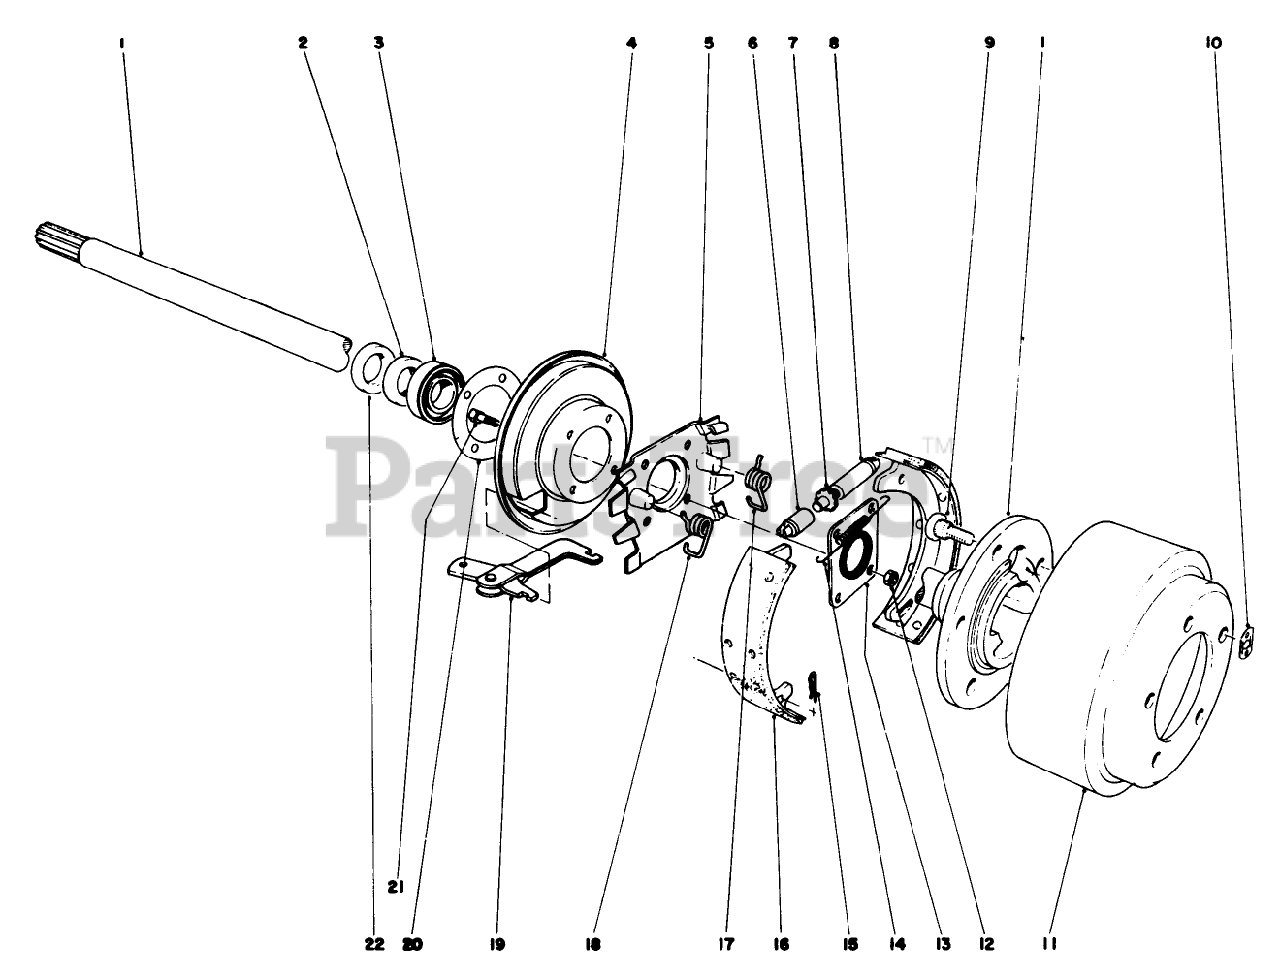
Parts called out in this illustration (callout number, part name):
3	BEARING ASM
4	SHIELD-DUST
5	SEE P.B.#734A
6	SOCKET-SCREW, ADJUSTING
7	SCREW-ADJUSTING
8	NUT-PIVOT
9	STUD-DRIVE
10	CLIP-RETAINING
12	NUT-HEX
13	SEAL-GREASE
14	SPRING-SCREW, ADJUSTING
15	RETAINER-LEVER, BRAKE
16	SEE PB #747
17	SPRING-RETURN, LH
18	SPRING-RETURN, RH
19	BRAKE LEVER ASSY
20	REFER TO(PB#807 OR MISC COMM SB#50)
22	RING-RETAINING, WHEEL BEARING
